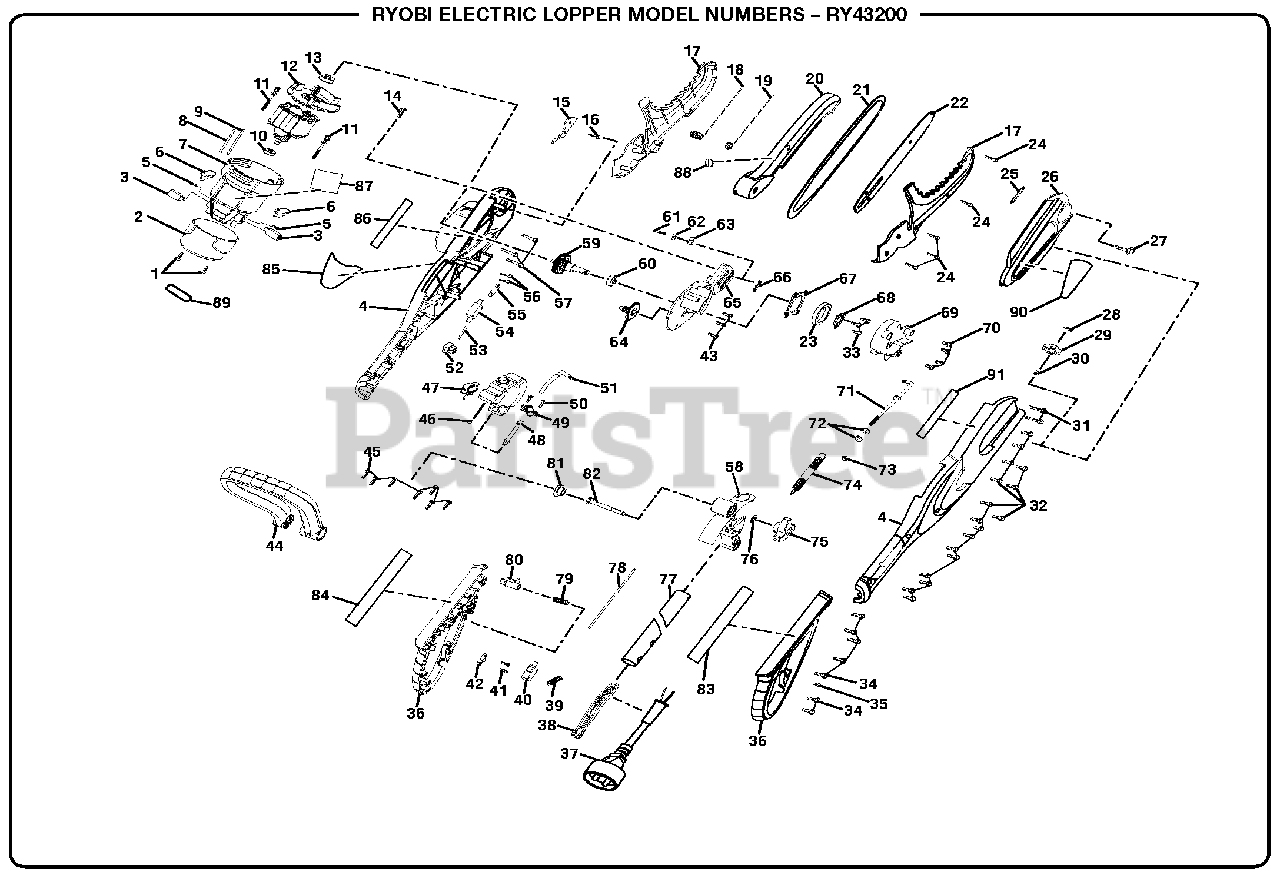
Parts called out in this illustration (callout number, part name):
1	Screw (M4 x 14 mm)
2	End Cap (Motor Housing)
3	Brush Assembly
4	Housing Assembly
5	Screw (M3 x 8 mm)
6	Wire Lead (1)
7	Motor Housing Assembly
8	Wire Lead (2)
9	Wire Lead (3)
10	Ball Bearing (607z)
11	Screw (M4 x 50 mm)
12	Motor Assembly
13	Ball Bearing (609z)
14	Screw (M4 x 14 mm)
15	Dust Cover
16	Screw (M3 x 8 mm)
17	Blade Clamp Assembly
18	Compression Spring (1)
19	Compression Spring (2)
20	Upper Blade Guard Assembly
22	Bar w/Graphics
23	Ball Bearing (6807z)
24	Screw (M4 x 8 mm)
25	Seal Ring
26	Chain Cover Assembly
27	Lock Screw (M8 x 40 mm)
28	Retaining Ring (E)
30	Compression Spring
31	Screw (M4 x 30 mm)
32	Screw (M4 x 14 mm)
33	Screw (M4 x 14 mm)
34	Screw (M4 x 14 mm)
35	Screw (M4 x 12 mm)
36	Handle Assembly
37	Power Cord Assembly
39	Compression Spring (Switch)
40	Micro Switch
41	Screw (M4 x 12 mm)
42	Switch Clamp
44	Axillary Handle Assembly
45	Screw (M4 x 14 mm)
47	Oil Tank Cap
48	Oil Inlet Tube Assembly
49	Oil Pump Assembly
50	Screw (M4 x 14 mm)
51	Oil Outlet Tube Assembly
52	Terminal Block
53	Wire Lead (4)
55	Switch Clamp
56	Screw (M3 x 12 mm)
57	Screw (M4 x 30 mm)
58	Drive Shaft
59	Output Shaft Assembly w/Bearing
60	Ball Bearing (626z)
61	Adjustment Bolt (M8)
62	Washer (M8)
63	Tensioning Nut
64	Worm Spindle Assembly
65	Chain Bar Holder Assembly
67	Bearing Bracket
68	Bearing Seat
69	Blade Guard Holder
70	Screw (M4 x 10 mm)
71	Tensioning Shaft
72	Washer (M6)
73	Lock Nut (M6)
74	Tension Spring
75	Front Handle Knob Assembly
76	Washer (M8)
77	Connecting Tube
78	Wire Lead (5)
79	Compression Spring
80	Lock-Out Button
81	Bolt Cover Front Handle
82	Hex Screw (M8 x 75 mm)
83	Icon Label
84	Warning Label (SP)
85	Ryobi Logo (Left)
86	Warning Label (EN/FR)
87	Data Label
88	No Hands Label
89	Ryobi Logo (Small)
90	Ryobi Logo (Right)
91	Warning Label (EN/FR)
